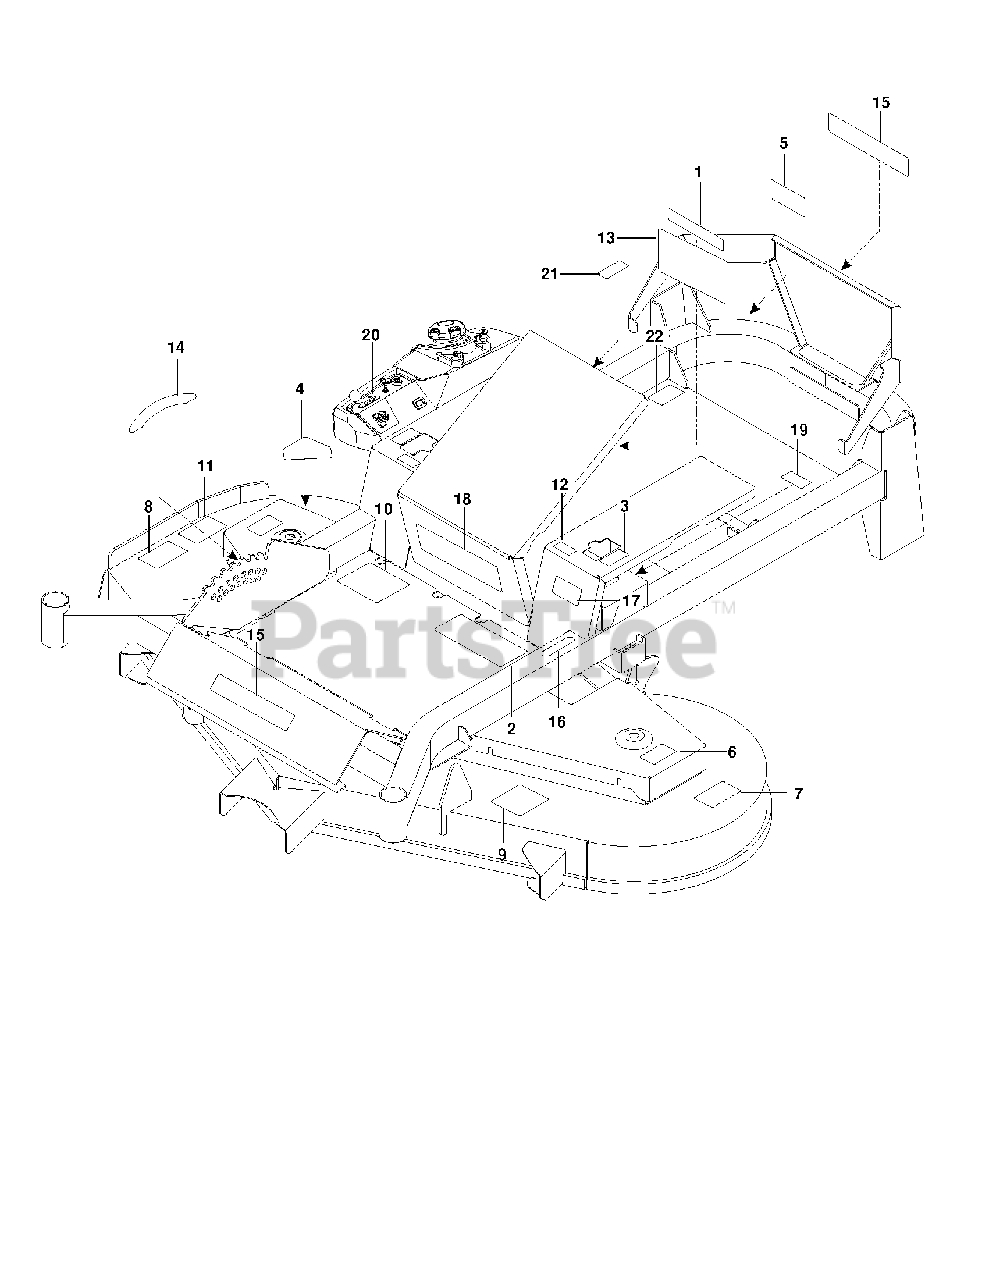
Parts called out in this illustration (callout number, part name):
2	DECAL, WARNING
3	DECAL, MOTION CONTROL
4	DECAL, CPSC
5	DECAL, BELT DRIVE
6	DECAL, NO STEP
8	DECAL, EURO SEVERING
9	DECAL, BELT ROUTING
10	DECAL, WARNING
12	DECAL, TRACKING
13	DECAL, SERVICE
14	DECAL, HEIGHT 5"
16	DECAL, PARK BRAKE
17	DECAL, FLAG
19	DECAL, FUEL
21	DECAL, WARNING SPARK ARRESTOR
22	DECAL, PROP. 65
